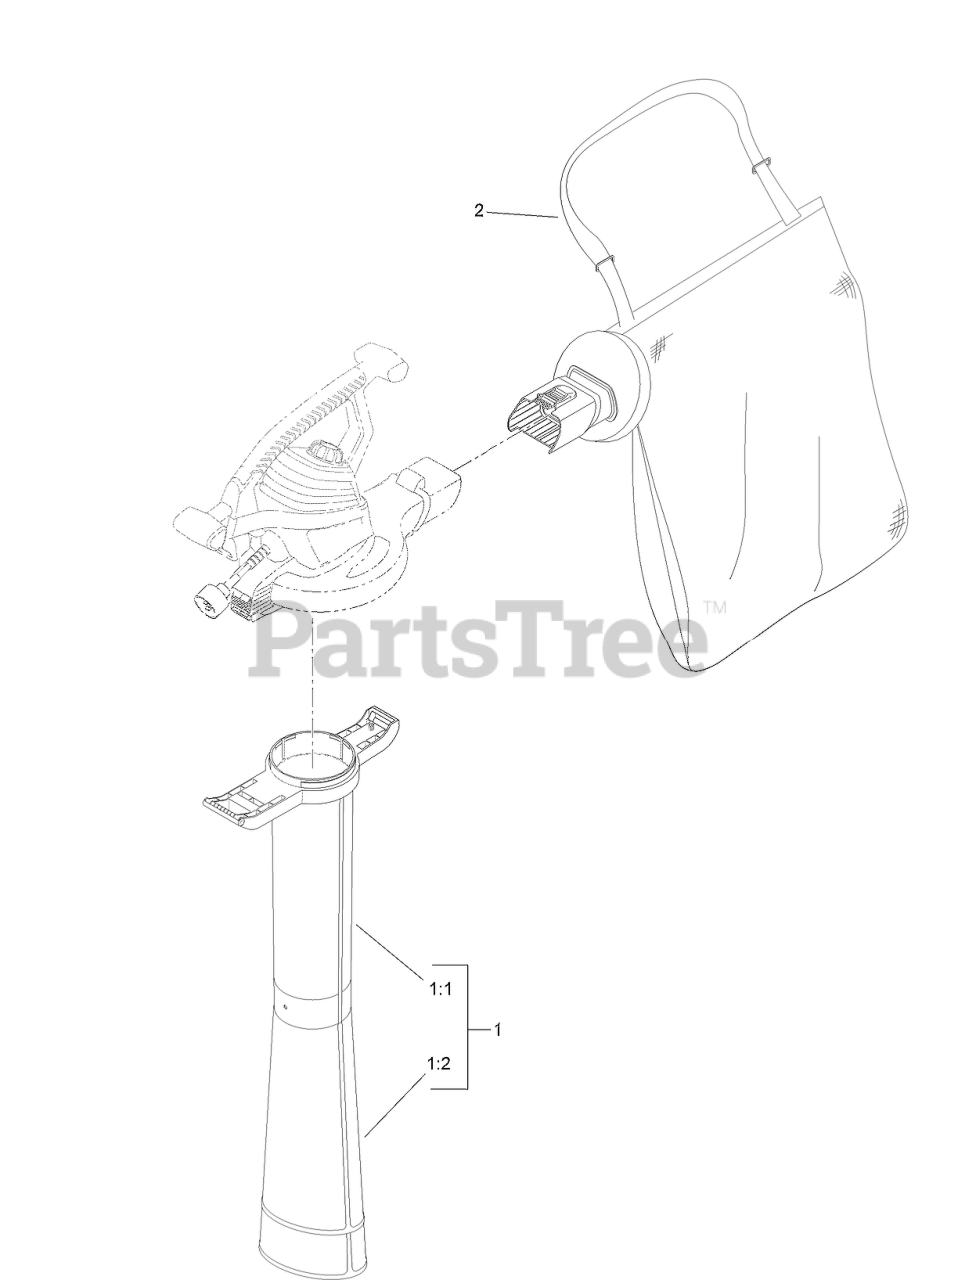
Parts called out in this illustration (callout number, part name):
1	VACUUM TUBE ASM
1:1	TUBE-VACUUM, UPPER
1:2	TUBE-VACUUM, LOWER
2	BOTTOM DUMP BAG ASM
